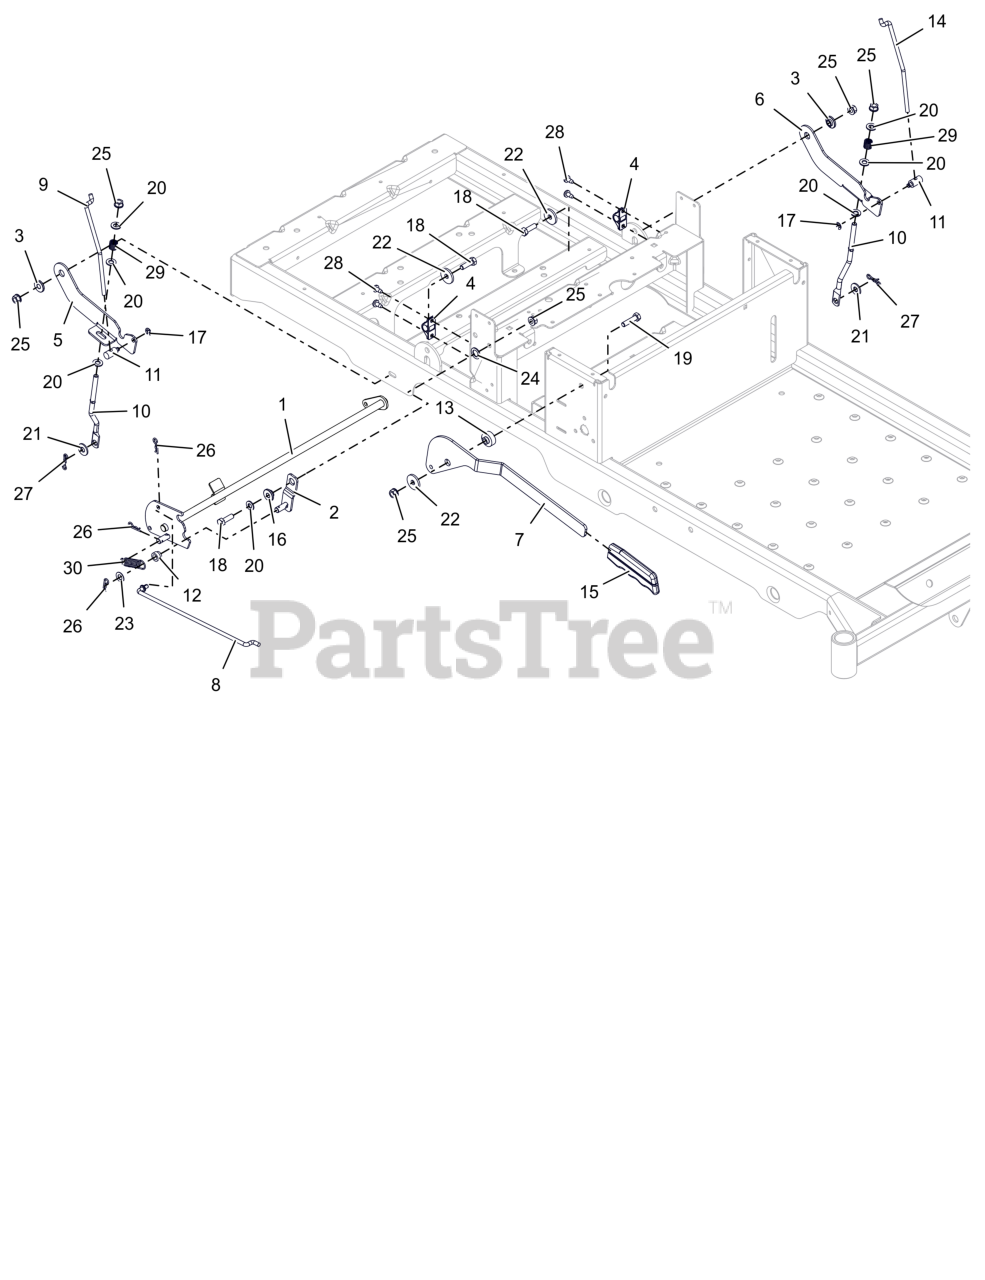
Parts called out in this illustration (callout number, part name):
1	WLDMT, BRAKE SHAFT (BLACK)
2	WELDMENT,DETENT ARM
3	BSHG, FLG .325X.499X.26X.88
4	BUSHING-.50 CLAMP BLOCK MOLDED
5	LATCH,RH NETURAL
6	LATCH,LH NETURAL
7	HANDLE, PARKING BRAKE
8	LINK, BRAKE HANDLE
9	LINK, NEUTRAL RH
10	LINK, BRAKE COG
11	TRUNION, 1/4-20
13	SPCR,BRAKE .32X.49X.192X1.00
14	LINK, NEUTRAL LH
15	GRIP, PARKING BRAKE (GREY)
16	BSHG-FLG .32X.500X.344X.880
17	RG-RTNG-EXT .250X.025
18	BLT,HEX .31-18X1.00 G5 ZCC
19	BLT, HEX .31-18X1.25 G5 ZCC
20	WSHR,FLT .344X.688X.065 ZCC
21	WSHR,FLT .375X.875X.083 ZCC
22	WSHR, FLT .340X1.125X.135 ZCC
23	WSHR, FLT .385X.745X.030 ZCC
24	WSHR, FLT .520X.827X.062 ZCC
25	NUT,LK-CTR-FLG .31-18 GF ZCC
26	PIN, HAIR #213 .08X1.19 ZCC
27	PIN, BOWTIE #72 ZCC
28	SCR, TAP .25-20X.5 PHD TRX ZCC
29	SPRING, COMPRESSION
30	SG-TENS .072X.565X1.87
